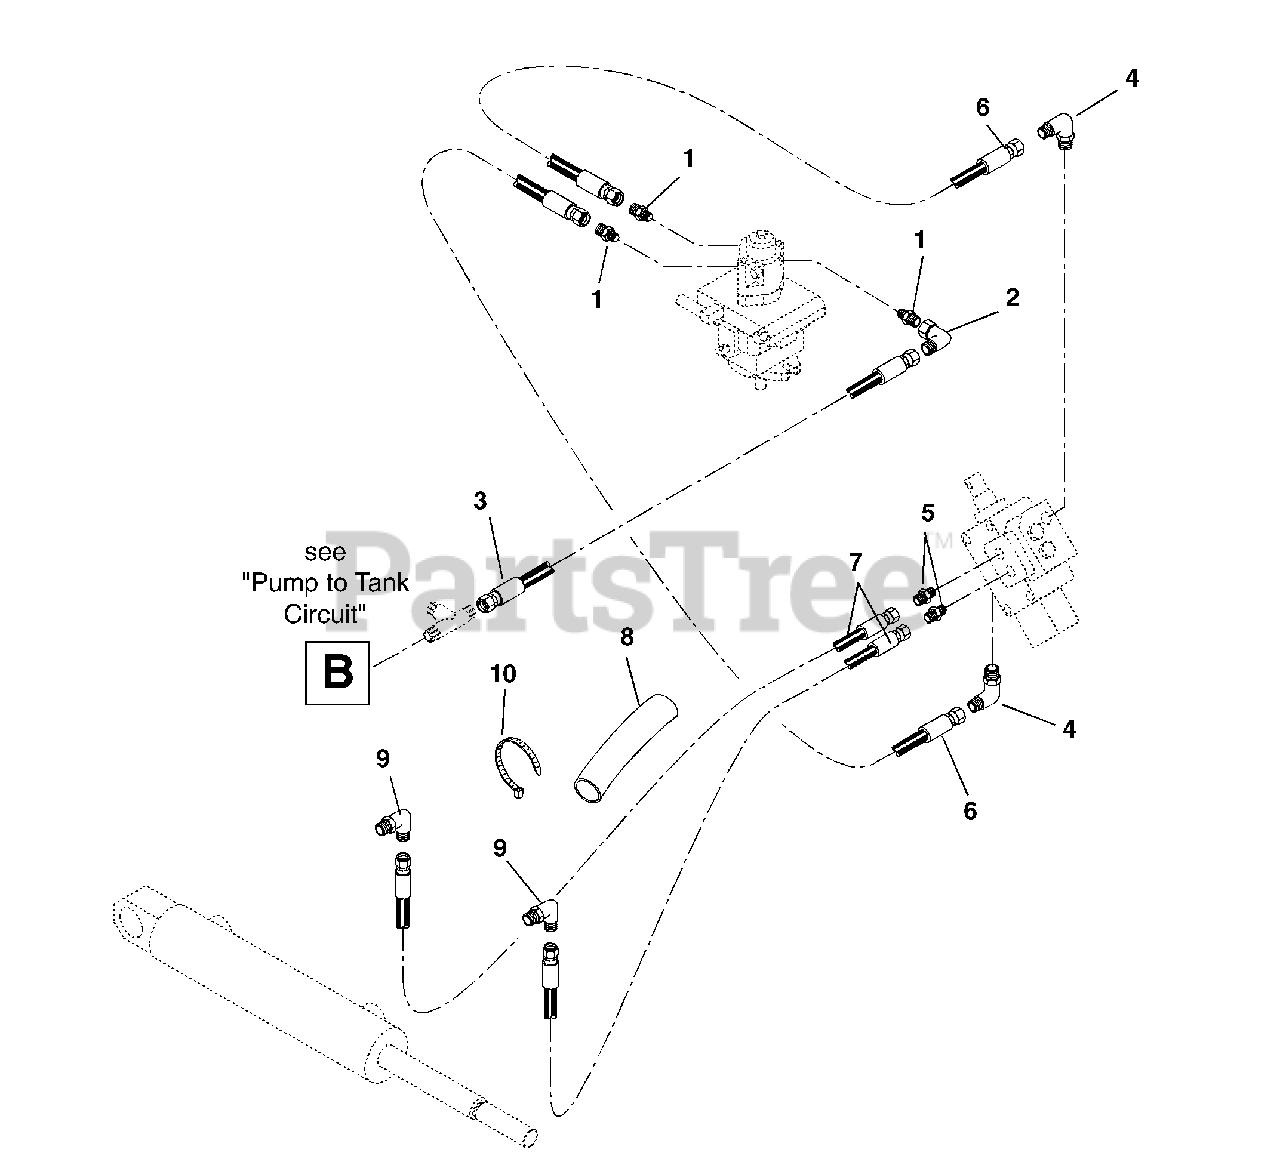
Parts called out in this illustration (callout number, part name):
2	Adapter
3	Hose-Hydraulic Valve to Tank
4	Adapter
5	Adapter
6	Hose Hydraulic .38 27.75 Long
7	Hose-Hydraulic .25 40.5" Long
8	Sleeve Protective 24"
9	Adapter
10	Cable Tie
